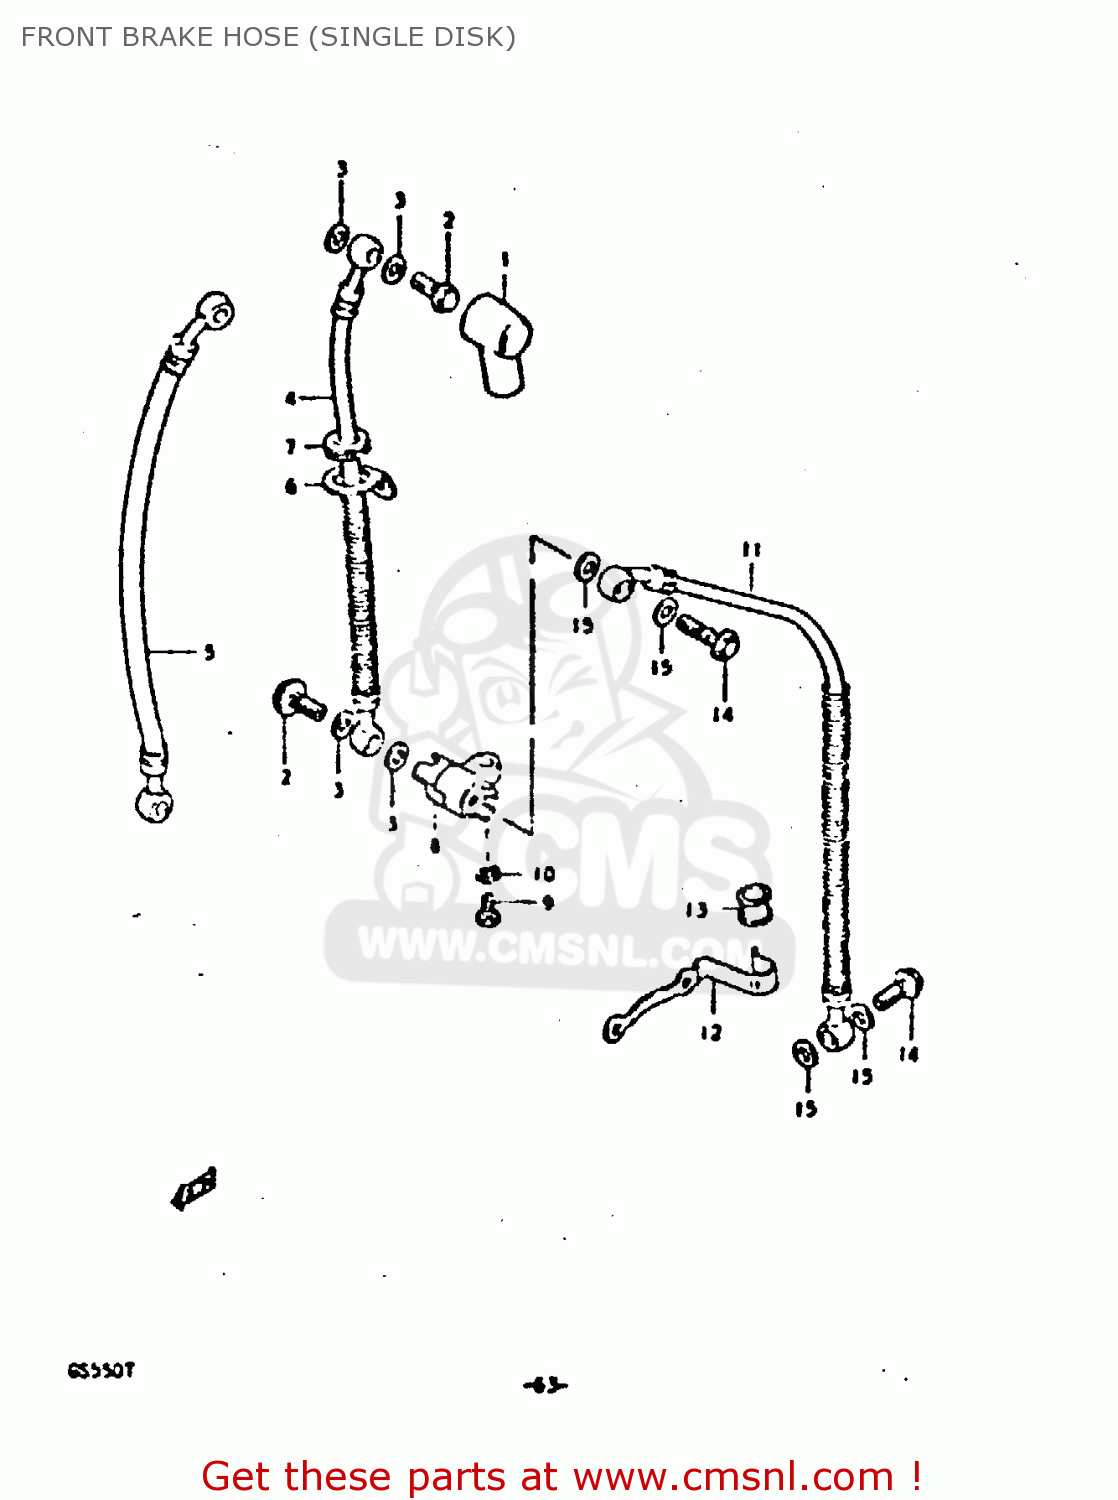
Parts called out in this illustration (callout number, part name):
1	BOOT,MASTER CYLINDER
2	BOLT,UNION
3	WASHER
4	HOSE,BRAKE NO.1
5	HOSE,FRONT BRAKE
6	GUIDE,BRAKE HOSE
7	GROMMET
8	JOINT,BRAKE HOSE
9	BOLT
10	LOCK WASHER
11	HOSE,BRAKE NO.2
12	GUIDE,BRAKE HOSE NO.2
13	BUSH,BRAKE HOSE GUIDE,NO.2
14	BOLT,UNION
15	WASHER
